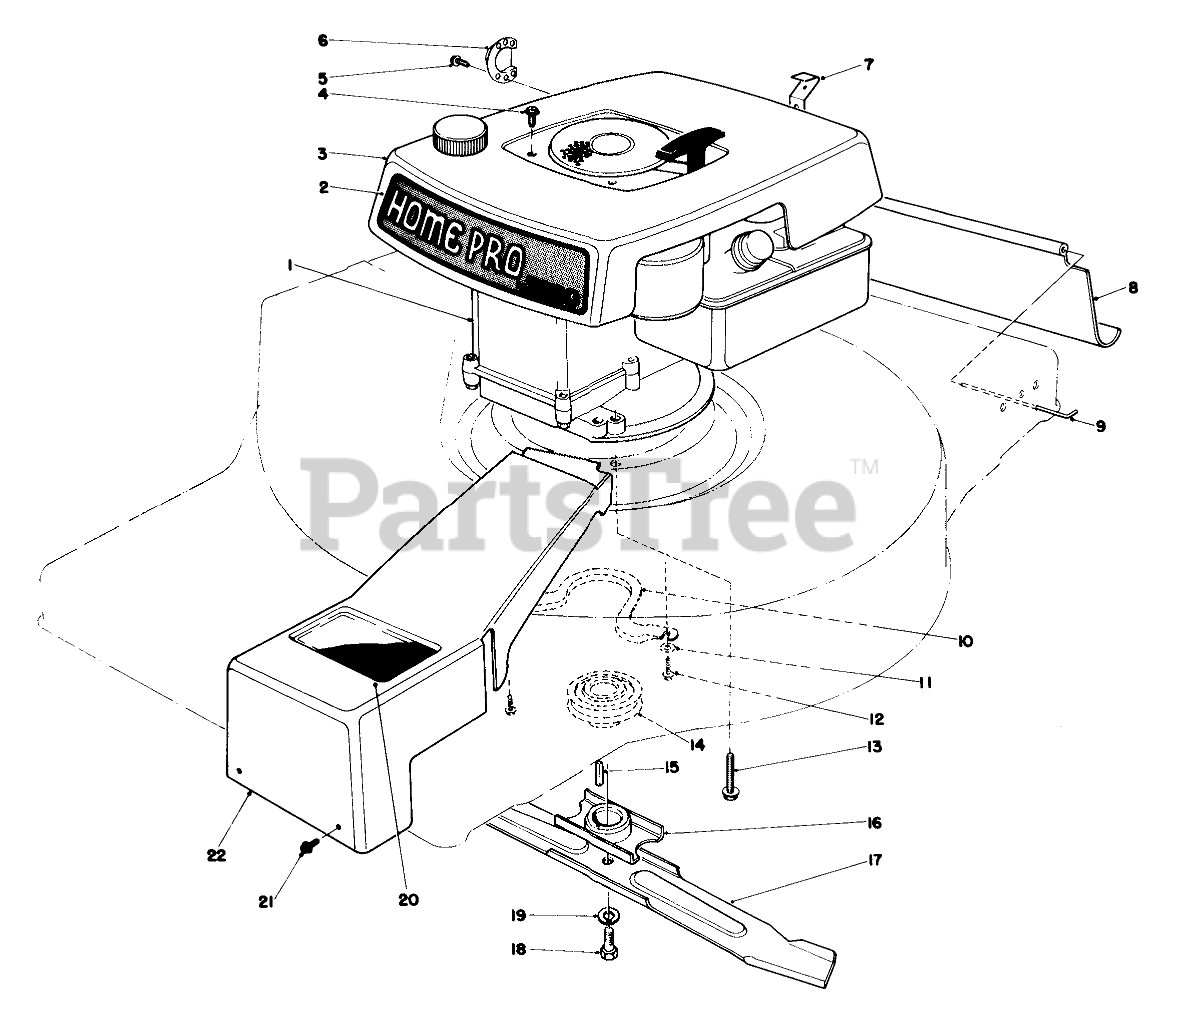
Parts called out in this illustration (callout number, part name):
1	Engine
2	Decal Shroud
3	Shroud
4	8X1/2 SELF TAP SCREW
5	SCREW W/ENGINE
6	Deflector
7	Bracket Control
8	SAF SHIELD REAR
9	SHIELD ROD
10	Belt Guide
11	WASHER-FLAT
12	SCREW THD 1/4 20 5/8
13	SCREW-HWHTF
14	DRIVER PULLEY
15	KEY-SQUARE
16	Blade Retailer
17	Blade
18	SPECIAL SCREW
19	WASHER-LOCK
20	Decal-Belt Cover
21	SCREW
22	Belt Cover
